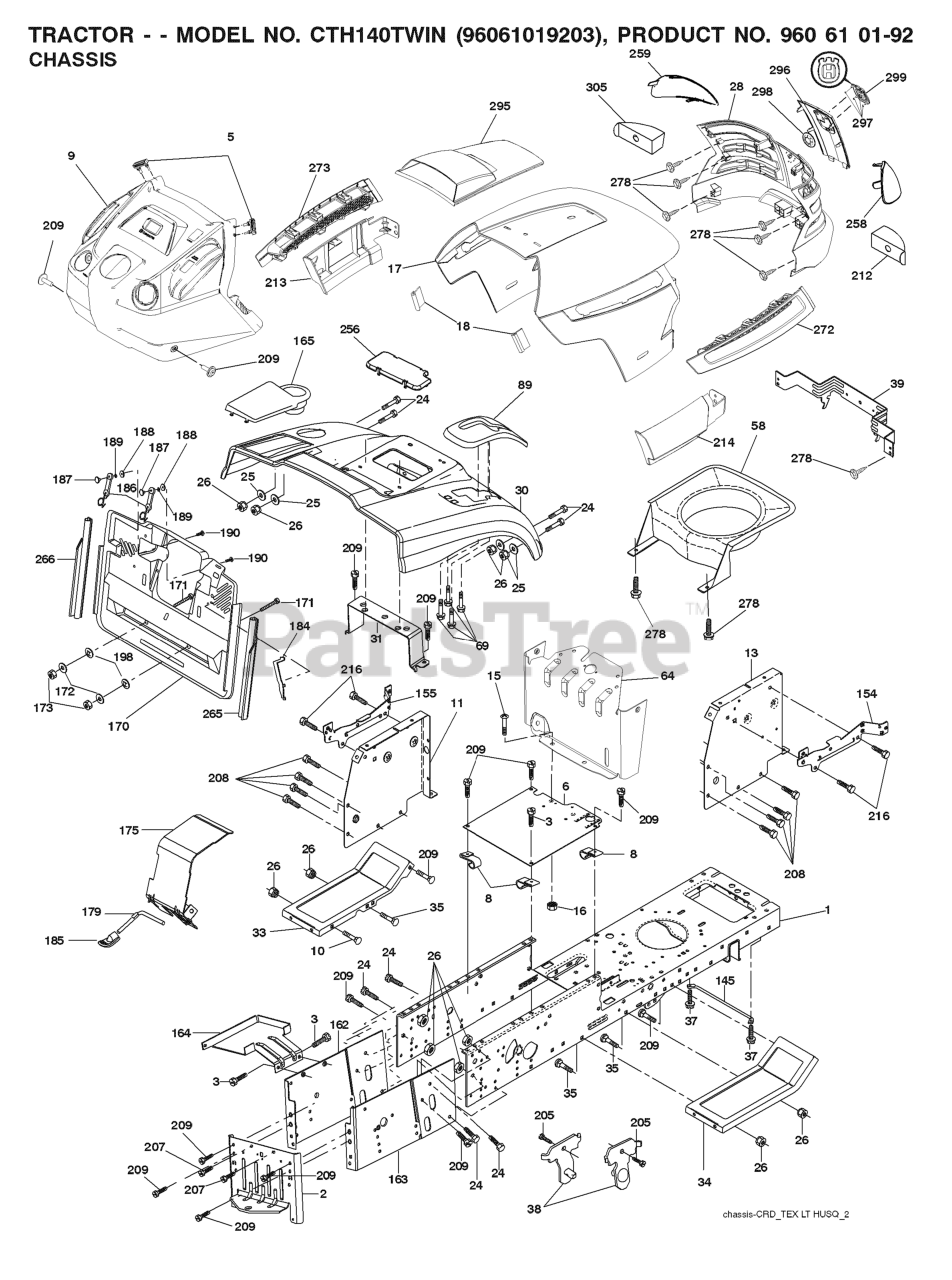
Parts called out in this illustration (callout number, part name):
2	DRAWBAR
3	SCREW 3/8-16X3/4
5	BUMPER DASH
6	PLATE
8	CLIP,INSULATOR
10	BOLT D
11	PANEL.DASH.LH.LTX
13	PANEL ASM, DASH RH
15	Screw, Machine, Truss Head 5/16-18 UNC x 3/4
16	NUT
17	HOOD
18	BUMPER.HOOD.TEX.HUSQVARNA
25	WASHER
26	NUT
28	RP GRILLE/LENS ASM.
30	CONSOLE.CRD.AUTO.GRY
31	BRACKET SUPPORT FENDER
33	FOOTREST PNT LH
34	FOOTREST PNT RH
37	Screw 5/16-18 x 1/2 Hex, Self Tapping 5/16-18 x 1/2
38	BRACKET ASM PIVOT MOWER REAR
39	BRACKET PIVOT
69	SCREW.HI-LO.CONSOLE
89	CONSOLE.CRD.AUTO.GREY.2005
145	ROD.PIVOT.HOOD
162	BRACKET
163	BRACKET EXTEN CHASSIS RH CRD
165	RP.COVER.BATTERY.CRD.GREY
172	WASHER
175	DOOR TRAP
179	ROD PIVOT FBI
184	BRACKET.ACTUATOR.BAGGER.SRD
186	LATCH ASSY
187	WELDNUT
189	LOCKWASHER #10
190	SCREW
207	SCREW, 5/16-18 X 1/2
208	SCREW 3/8-16X1/2
209	SCREW, 3/8-16X3/4
212	INSERT REFLECTIVE
213	SKIRT SIDE LH
214	SKIRT SIDE RH
216	SCREW HEXWSHR 1/4-20X3/4
256	COVER FENDER CRD
258	LENS.HUSQVARNA LT.RH
259	LENS.HUSQVARNA LT.LH
265	SEALING
266	SEALING
272	VENT SIDE HOOD LH
273	VENT SIDE HOOD RH
278	SCREW.#10 X 0.750.BOS
295	VENT TOP HOOD
296	TRIM
297	CLIP.RETAINER.TINNER.
298	NUT PUSH M
299	RP LOGO
305	INSERT.REFLECTIVE.RH.
